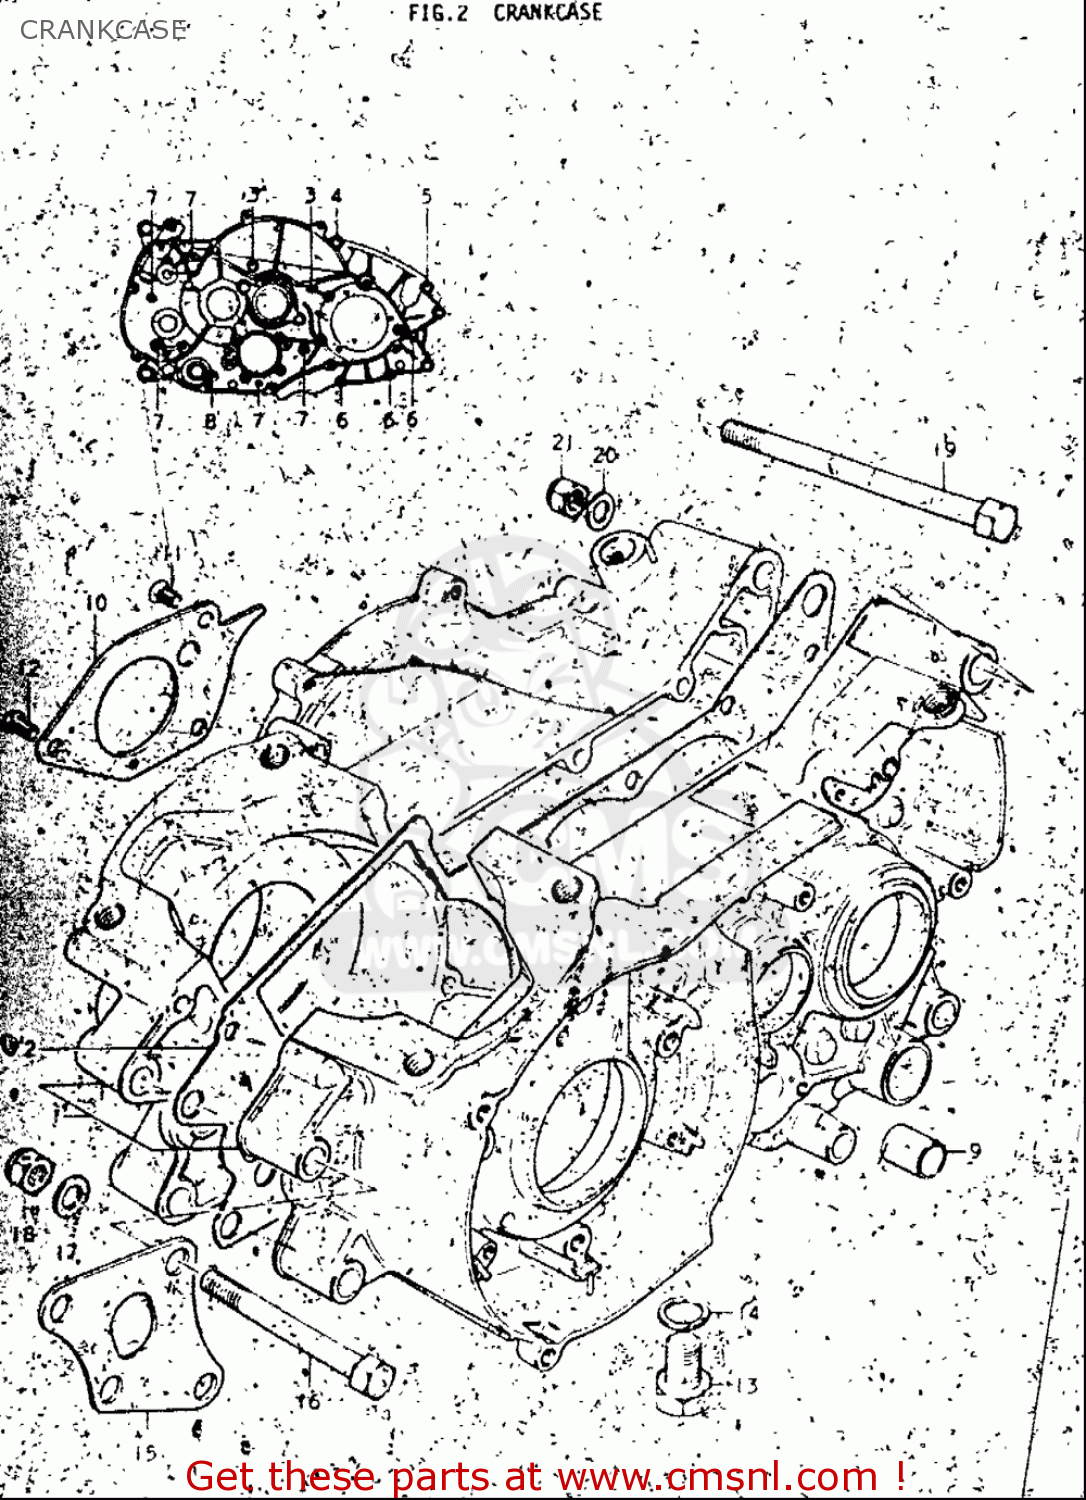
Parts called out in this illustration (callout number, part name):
2	GASKET,CRANKCASE (NAS)
3	SCREW
4	SCREW
5	SCREW
6	SCREW
7	SCREW
8	SCREW
9	PIN
11	SCREW
12	SCREW
13	PLUG
14	GASKET(14X19.2X2) (NAS)
15	PLATE,ENGINE MOUNTING
16	BOLT
17	WASHER
18	NUT
19	BOLT(10X120)
20	WASHER
21	NUT
